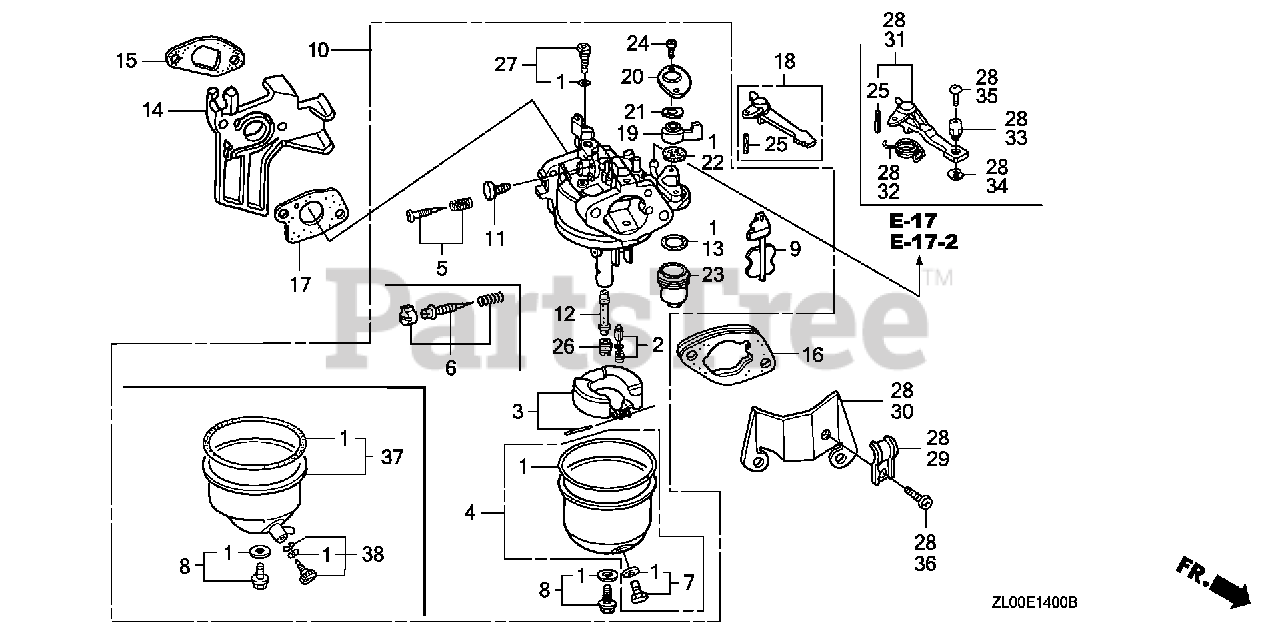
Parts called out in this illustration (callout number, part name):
1	GASKET SET
2	VALVE SET, FLOAT (SEAT NOT INCLUDED)
4	CHAMBER SET, FLOAT (CARBURETOR NO.)
5	SCREW SET, PILOT (CARBURETOR NO.)
7	SCREW SET, DRAIN
8	SCREW SET
10	CARBURETOR ASSY. (BE64C B)
11	SCREW, THROTTLE STOP
12	NOZZLE, MAIN
13	GASKET, FUEL STRAINER CUP
14	INSULATOR, CARBURETOR
15	GASKET, INSULATOR
16	SPACER, CARBURETOR
17	GASKET, CARBURETOR
18	LEVER, CHOKE (STD)
19	LEVER, VALVE
19	LEVER, PETCOCK (CARBURETOR NO.)
20	PLATE, LEVER SETTING (CARBURETOR NO.)
21	SPRING, PETCOCK LEVER
22	GASKET, PETCOCK
23	CUP, FUEL STRAINER
24	SCREW, PAN (3X6)
24	SCREW, PAN (3X8) (CARBURETOR NO.)
25	PIN, SPRING (2X12)
26	JET, MAIN (#70) (CARBURETOR NO.)
26	JET, MAIN (#72) (CARBURETOR NO.)
26	JET, MAIN (#75) (CARBURETOR NO.)
26	JET, MAIN (#70)
27	JET SET, PILOT (#45)
